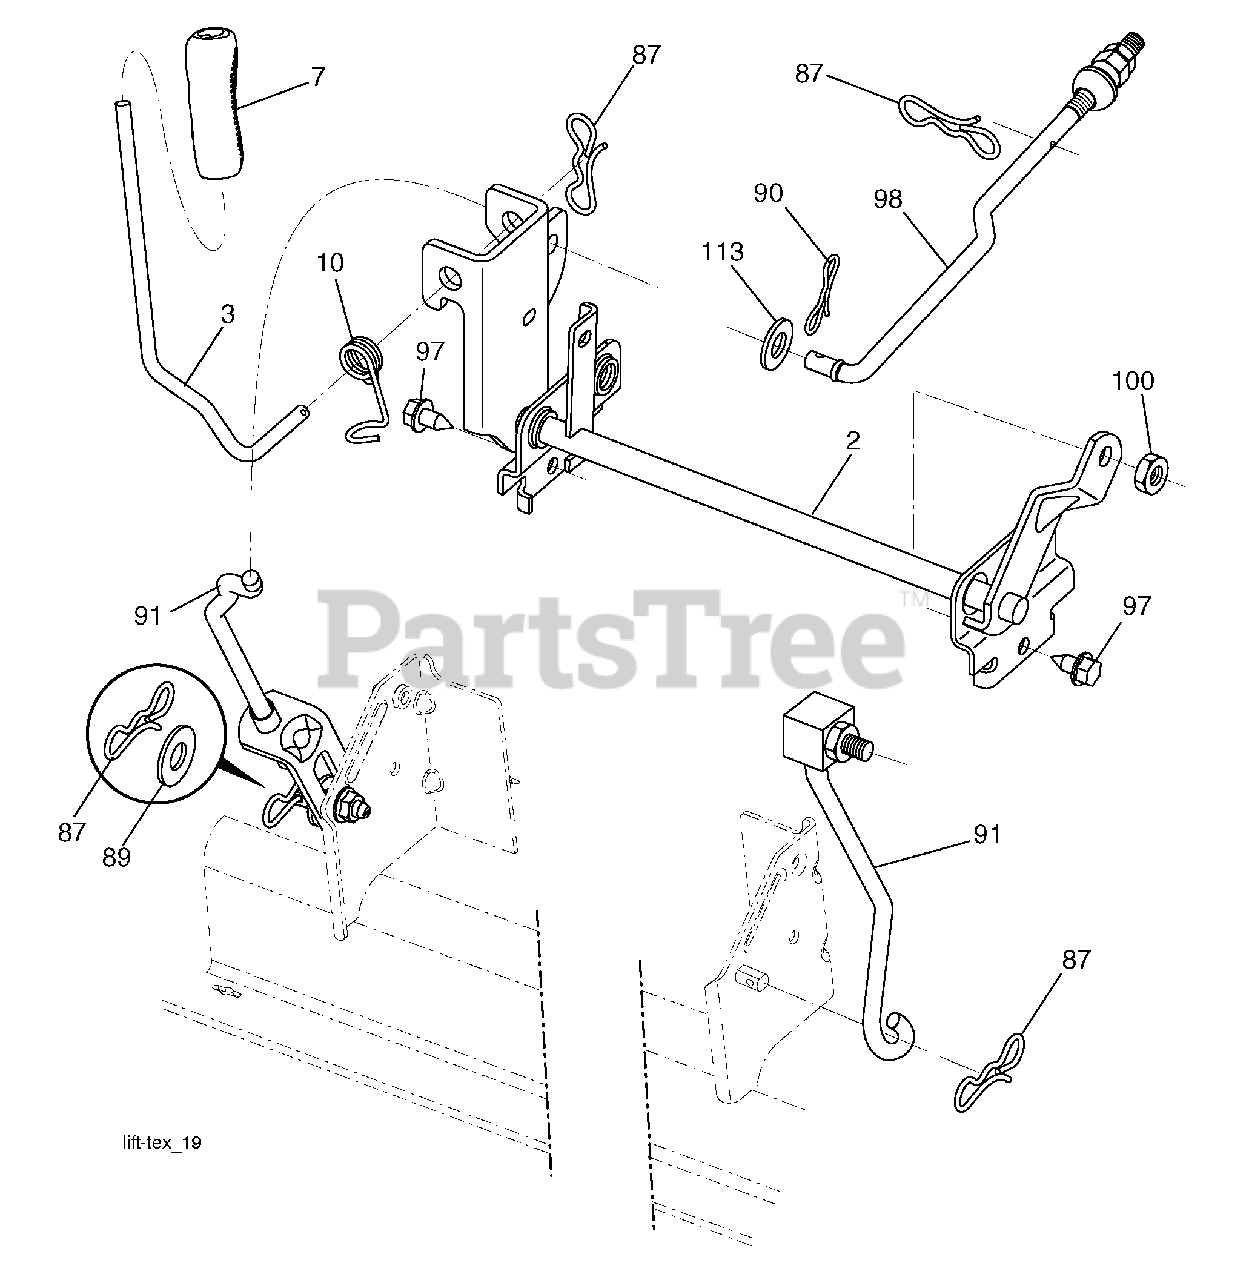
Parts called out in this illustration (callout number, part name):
2	Shaft Asm., Lift
3	Lever Asm., Lift
7	Grip, Lever
10	Spring Torsion
87	Pin Cotter 7/16 Bow Tie Lock
88	Spring Lift Assist
89	Washer Clear Zinc
90	Pin Cotter 5/16 Bow Tie Lock
91	Link Lift Susp Mower Rear
97	Screw 3/8-16 x 3/4
98	Link Lift Susp. Front Mower
100	Nut Centerlock 3/8-16 unc
113	Washer 17/32 x 1-3/16 x 12 Ga.
